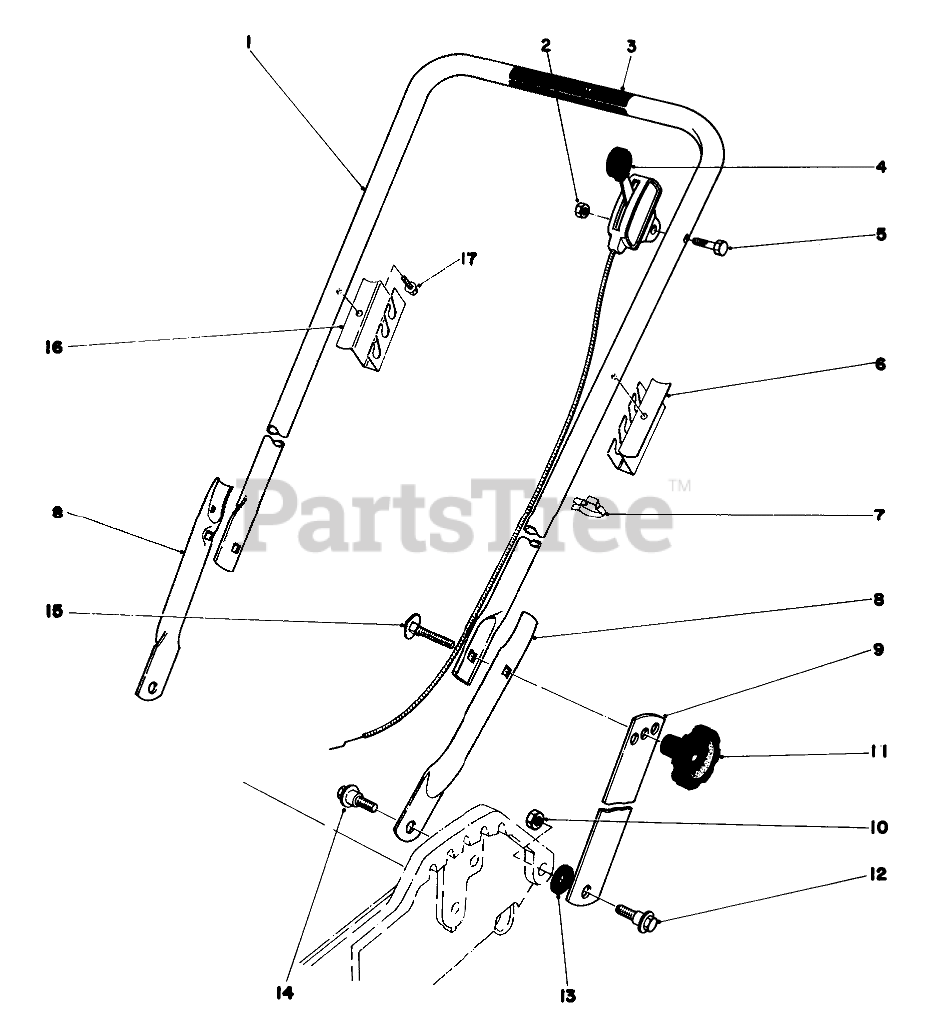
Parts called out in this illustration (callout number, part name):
1	Handle-Upper
2	NUT-LOCK
3	Danger-Decal
4	Throttle Control
5	SCREW-HH
6	SUPPORT BAG LH
7	BOWDEN CLIP
8	Hand-Lower
9	18" HANDLE LATCH
10	Nut
12	SCREW-SHOULDER
13	SPACER
14	SCREW-SHOULDER
15	SCREW-HANDLE
16	SUPPORT BAG RH
17	SCREW-HWHTF
